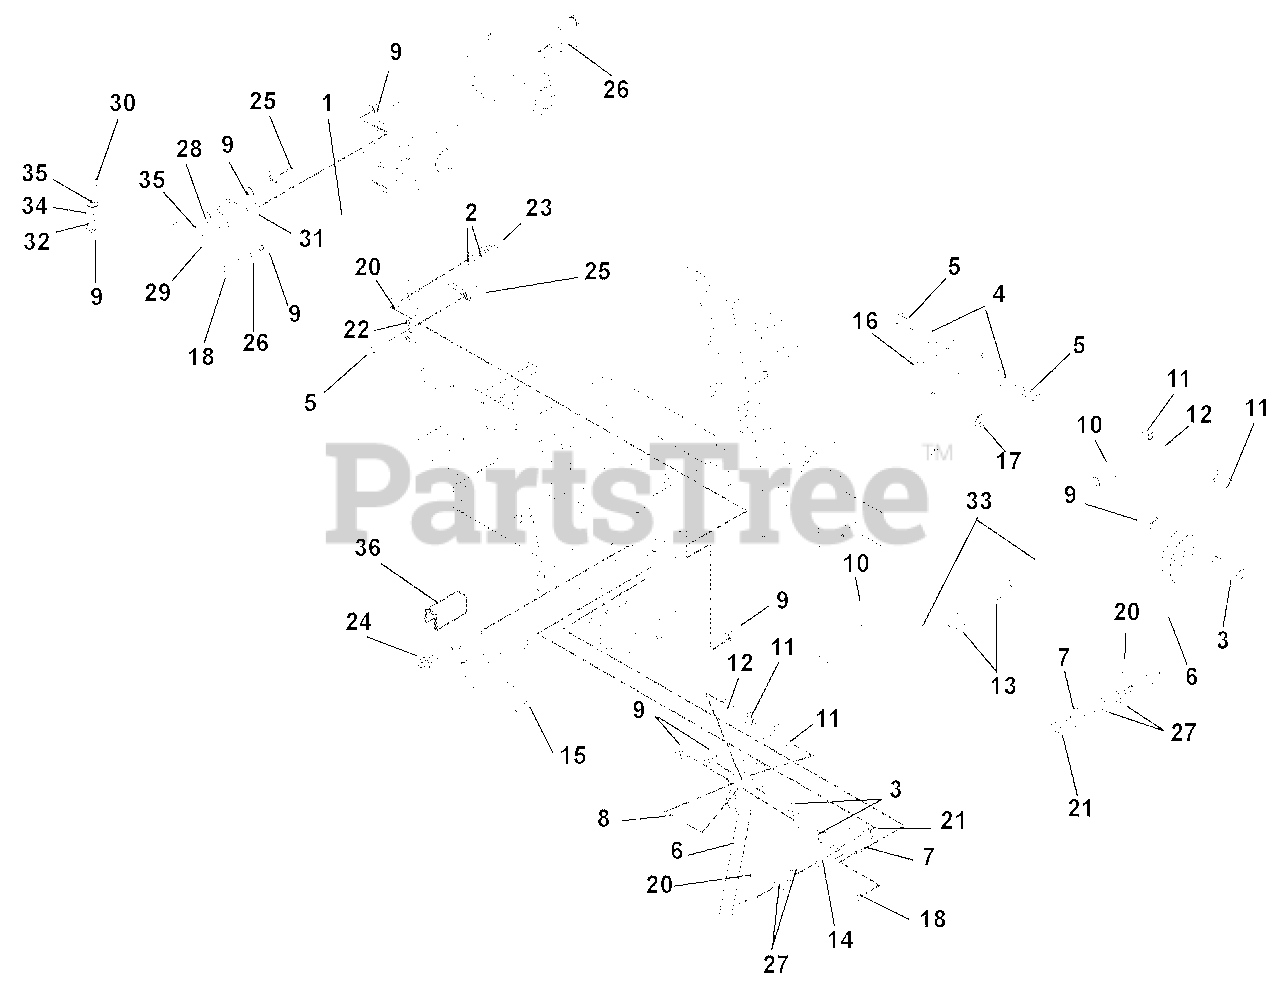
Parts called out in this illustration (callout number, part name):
1	Assembly, Steering Rod .38 Rod x 21.65
2	Washer, Flat Steel .408 x .812 x .065
3	Bolt, Hex .31-18 x 1.75 Grade 5
4	Nut, Hex Jam .375-16
5	Bolt, Hex .375-16 x 1.75
6	Weldment, Control Arm
7	Bushing, Flange
8	Eccentric
9	Nut, Locking Top Flange .31-18
10	Handle Weldment Left Hand
11	Bushing, Flange Nylon .762 x 1.48 x .44
13	Grip, Handlebar
14	Bushing .625 x .75 x .50
15	Bracket, Stop Right Hand
16	Bracket, Stop Left Hand
17	Screw, Tapping .38-16 x .75 Hex Washer Head
18	Bolt, Hex .31-18 x .75 Grade 5
19	Washer, Locking .38 x .094 Regular
20	Key, Woodruff .13 x .63
21	Washer, Wave
22	Weldment, Pivot Arm
23	Nut, Locking Top Flange .38-16
24	Screw, Tapping .38-16 x .50 Hex Washer Head
25	Nut, Locking Jam Center .375-16
26	Weldment, Return to Neutral/Damper/Rod End
27	Washer, Flat Steel .63 x 1.005 x .062
28	Washer, Locking .31 x .078
29	Bolt, Hex .31-18 x 1.25 Grade 5
30	Damper, Stabilus
31	Spacer .318 x .43 x .375
32	Washer, Flat Steel .38 x .875 x .083
33	Tube, .88ID x 1.00 OD x 10.75
34	Washer, Flat Steel .328 x 1.00 x .094
35	Stud, Ball, Threaded
36	Strip, Cowl
